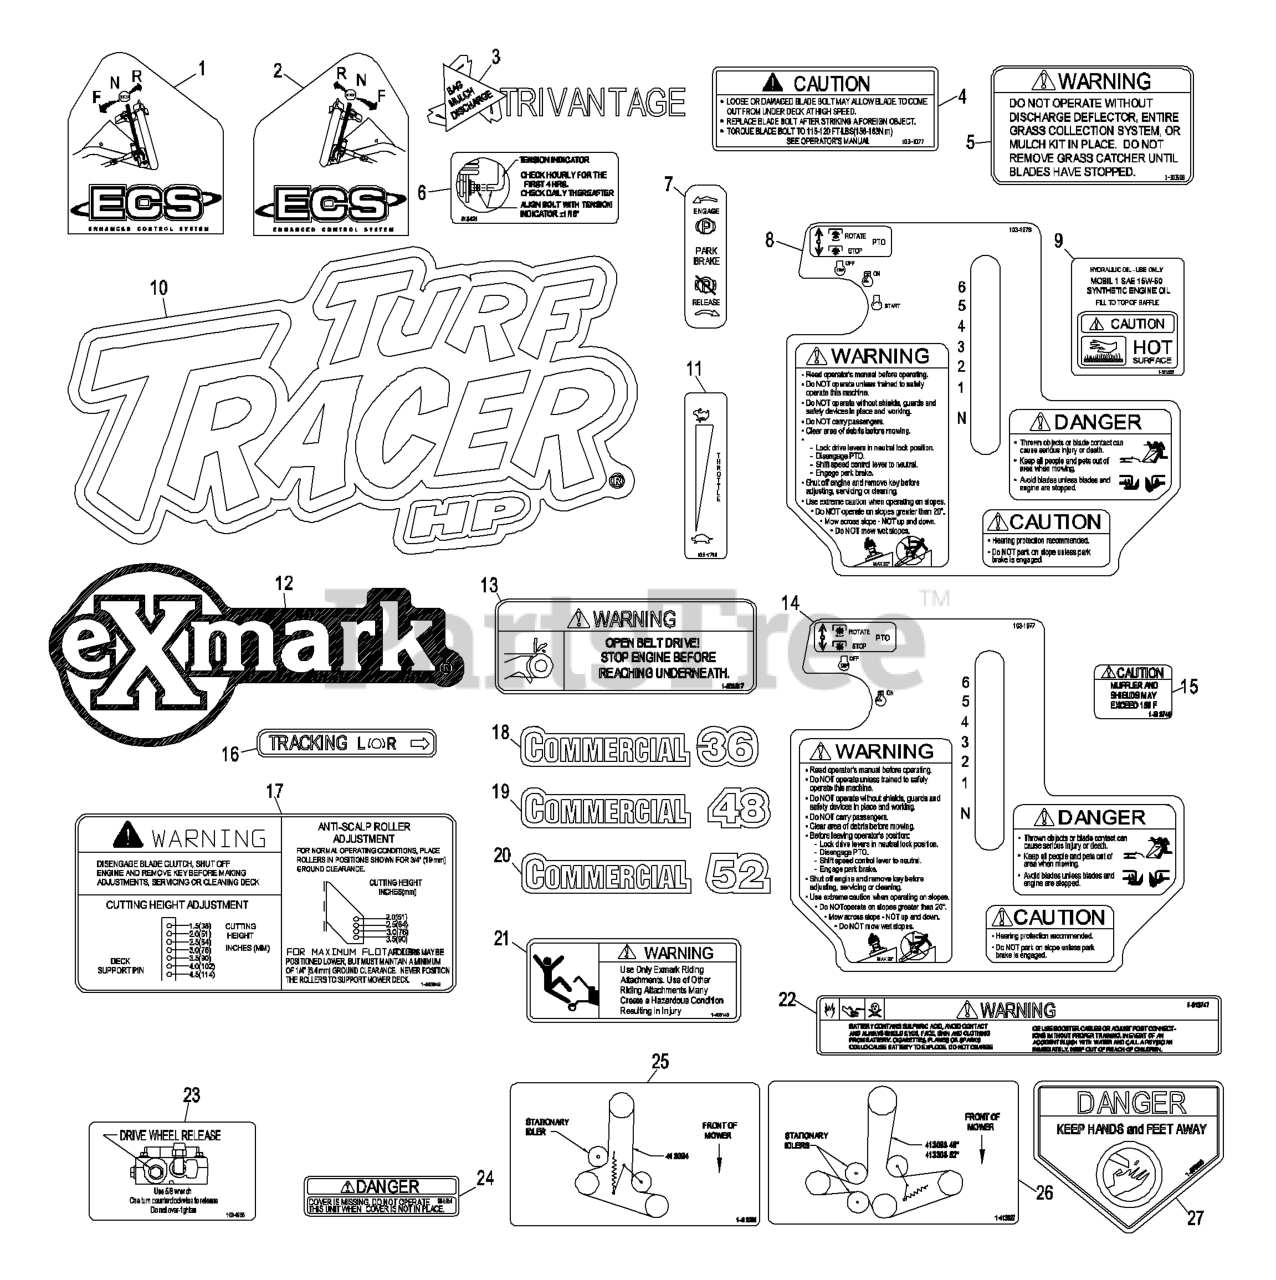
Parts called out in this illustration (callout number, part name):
1	DECAL,LH ECS INSTRUCTION
2	DECAL,RH ECS INSTRUCTION
4	DECAL,BOLT TORQUE
5	DECAL-WARNING, DISCHARGE
6	DECAL,INDICATOR
7	DECAL-BRAKE, PARK
8	DECAL,CONSOLE
10	DECAL,TTHP MODEL
11	DECAL,THROTTLE ONLY
13	DECAL,BELT DRIVE
14	DECAL,ECS CONSOLE
16	DECAL,TRACKING ADJUST
17	DECAL,ANTI SCALP
18	DECAL,COMMERCIAL 36
19	DECAL,COMMERCIAL 48
20	DECAL,COMMERCIAL 52
21	DECAL,SULKY WARNING
22	DECAL-BATTERY
23	DECAL,DRIVE RELEASE
24	DECAL-COVER, MISSING
25	DECAL,BELT ROUTING
26	DECAL,BELT ROUTING
27	DECAL-DANGER
